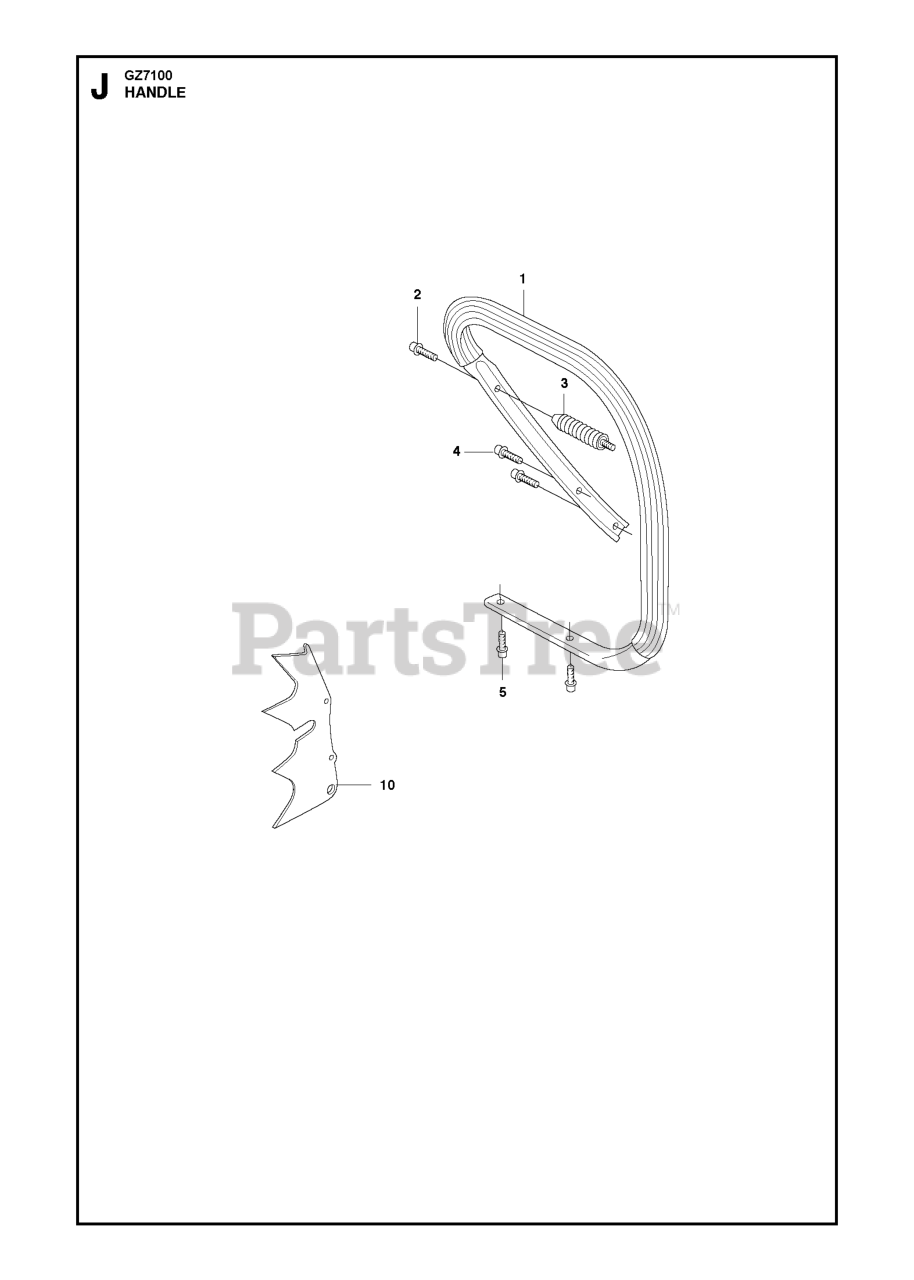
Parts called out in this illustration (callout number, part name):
1	FRONT HANDLE ASSY
2	SCREW ITXSCFT PW6.3X22 T27 8.
3	ANTIVIBE MOUNT
3	VIBRATION ABSORBER
4	SCREW ITXSCFT PW5.5X16 T27 8.
5	SCREW ITXSCFT PW5.5X16 T27 8.
10	FELLING DOG
